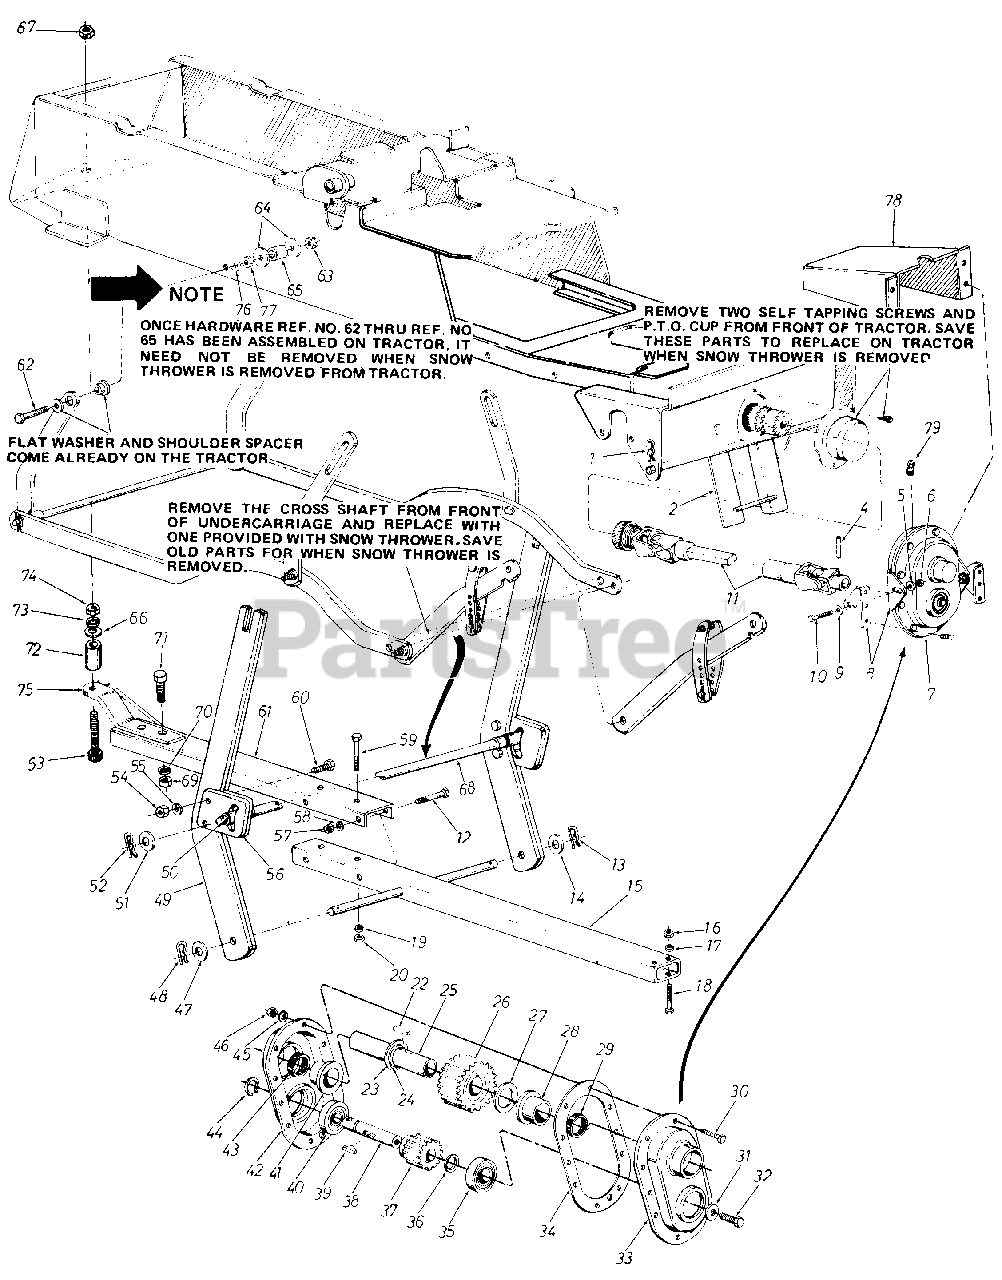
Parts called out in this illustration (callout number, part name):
1	Intern. Cotter Pin 3/4" D ia.
2	Guide Bracket Ass'y.
4	Spring Pin Spirol 1/4 " Dia. x Lg.
5	Belleville Wash. .341 " I.D. x .88" O.D.
6	Hex Nut 5/16-18 Thd.*
7	Gear Box Ass'y. Comp.
8	Gear Box Support Brkt.
9	Belleville Wash. .341" I.D. x .88" O.D.
10	Hex Scr 5/16-18 x .75" Lg. *
11	Universal Drive Shaft Ass'y.
12	Hex Scr. 3/8-24 x 4.50" Lg.*
13	Hair Pin Cotter
14	Fl. Wash. .75" I.D. x 1.5"
15	Lift Shaft Ass'y.
16	Hex Ins. Jam L.-Nut 3/8-24 Thd.
17	L.-Wash. 3/8" Scr.*
18	Hex Scr. 3/8-24 x 2.75" Lg.*
19	L.-Wash. 3/8" Scr.*
20	Hex lns. Jam L.-Nut 3/8-24 Thd.
22	Hi-Pro Key 1/4" x 7/8" Dia.
23	Fl.-Wash. 1.31" I.D. x 2.00" O.D. x .060
24	Snap Rinq for 1.25" Dia. Shaft
25	Gear Shaft 1.25" Dia. x 6.0" Lg.
26	28 Teeth Spur Gear
27	Fl.-Wash. 1.31" I.D. x 2.00 0 O.D. x .060
28	Flange Bearing 1.25" I.D. x 1.75" O.D.
29	Oil Seal 1.25" I.D. x 1.75" O.D. x .26
30	Hex Scr. 1/4-28 x .88" Lg.
31	Fl.-Wash. .40 I.D. x 1.25" O.D. x .160
32	Hex L.-Scr. 3/8-24 x 1.00" Lg.
33	Complete Gear Housing Half-L.H.
35	Ball Bearing 1.00" I.D. x 2.00" 0. D .
36	Fl.-Wash. 1.03" I.D. x 1.63" x .090
37	15 Teeth Spur Gear
39	Woodruff Key 1/4" x 3/4" Dia.
40	Ball Bearing 1.00" I.D. x 2.00" O.D.
41	Flange Bearing 1.25" I.D. x 1.75" O.D.
42	Complete Gear Housing Half-R.H.
43	Oil Seal 1.25" I.D. x 1.75" O.D. x .26
44	Snap Ring for 1.00" Dia. Shaft
45	Spring Wash. 1/4" I.D.
46	Hex Nut 1/4-28 Thd.
47	Fl. Wash. .75" I.D. x 1.5"
48	Hair Pin Cotter
51	Fl.-Wash. .62" I.D. x 1.12" O.D.
52	Hair Pin Cotter
53	Hex Bolt 5/8-18 x 4.00" Lg.
54	Hex Nut 5/16-18 Thd.*
55	L.-Wash. 5/16" Scr.
58	L.-Wash. 3/8" Scr.*
59	Hex Scr. 3/8-24 x 2.75"
60	Hex Scr. 5/16-18 x 1.00" Lg. *
61	Lift Bracket
62	Hex Scr. 3/8-24 x 2.50"
63	Hex Jam L.-Nut 3/8-24 Thd.
64	Fl.-Wash. .375 I.D. x 1.00" O.D. x .135"
65	Spacer .275 I.D. x .625 O.D. x .440
66	Fl.-Wash. .62" I.D. x 1.12" O.D.
67	Hex Jam L.-Nut 5/8-11 Thd.
68	Cross ShaftAss y.
69	Hex Nut 1/2-13 Thd.*
70	L.-Wash. 1/2" Scr.*
71	Hex Scr. 1/2-13 x 1.25"
73	L.-Wash. 5/8" Scr.*
74	Hex Jam Nut 5/8-11 Thd.
77	Hex Nut 3/8-24 Thd. *
78	Drive ShaftCover
79	Grease Fitting
